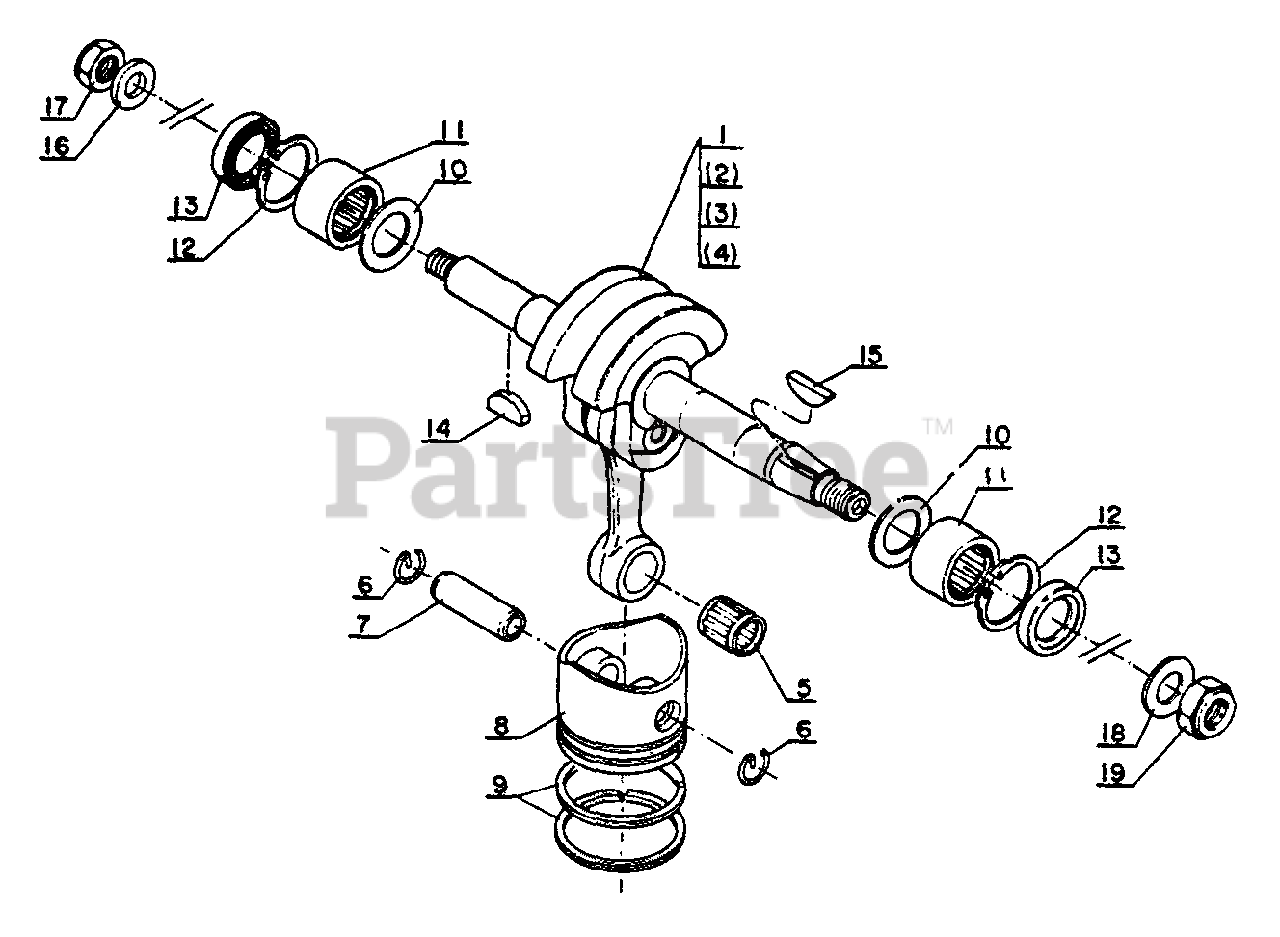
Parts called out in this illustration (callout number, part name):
1	CRANKSHAFT ASSY
5	BEARING, NEEDLE 8
6	RING, SNAP
7	PIN, PISTON
8	PISTON
9	RING, PISTON
10	SIDE PLATE
11	BEARING, NEEDLE
12	RING, RETAINING
13	SEAL, OIL
16	WASHER 6
17	LOCKNUT - 6
18	WASHER 8.5×16×1.2
19	LOCKNUT
